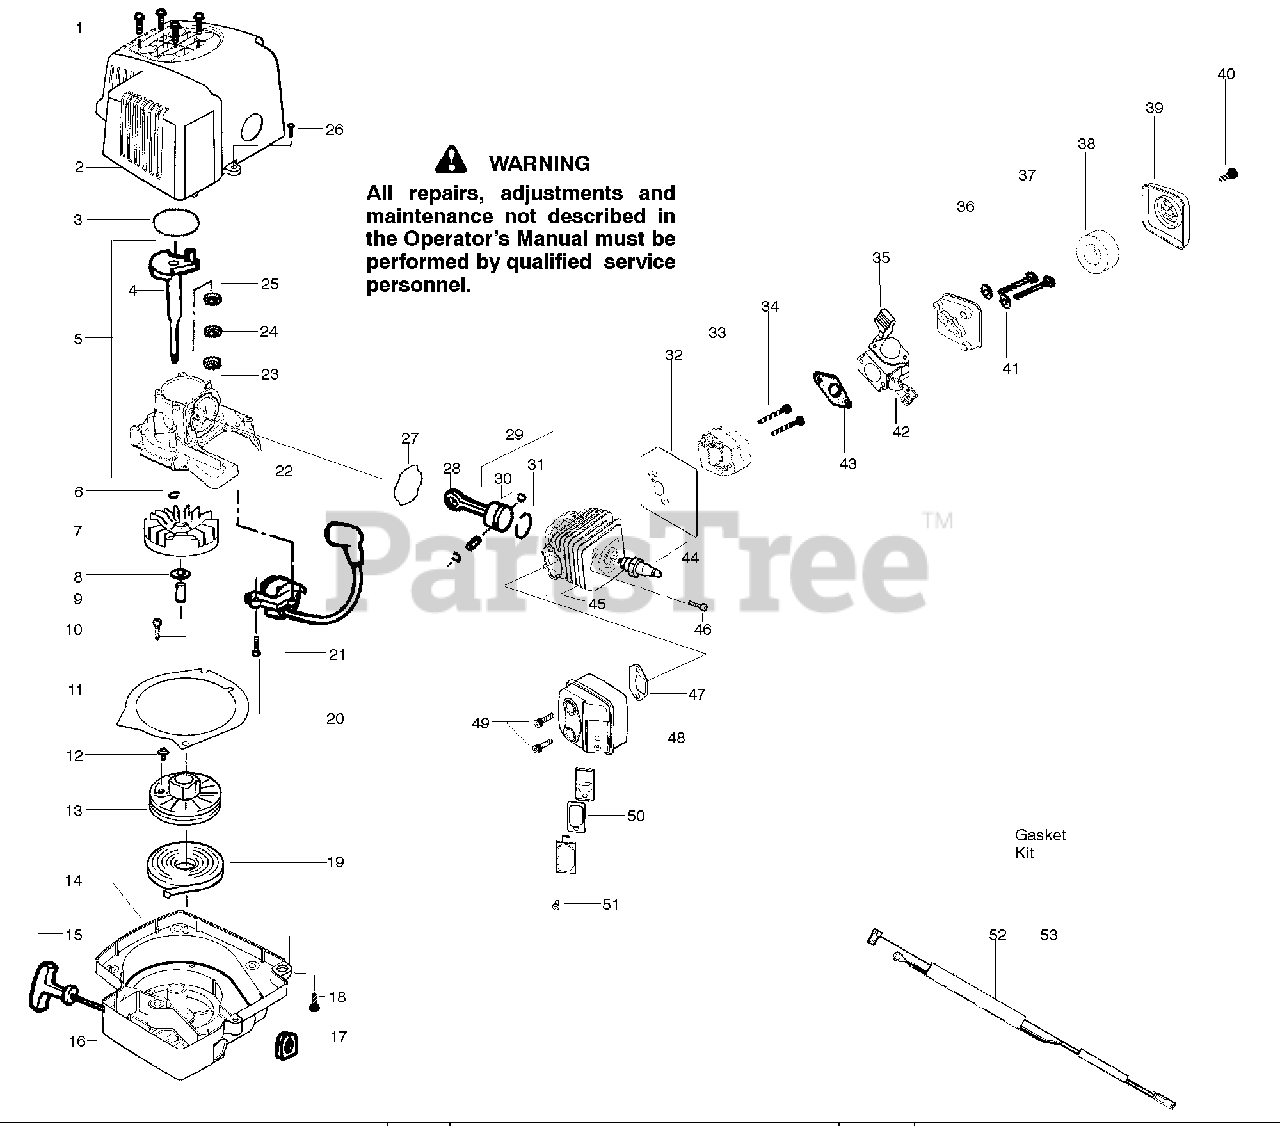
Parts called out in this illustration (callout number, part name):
2	Assy-Shroud/H'shield
3	O-Ring-C'case (kit)
4	Assy-Crankshaft
5	Assy-C/case-C/shaft
6	Ring-Retainer-C'shaft
7	Assy-Flywheel
9	Spacer-Flywheel
13	Kit-Starter Pulley
14	Assy-Fan Housing
15	Handle-Starter
17	Grommet-Ignition Module
18	Screw-(f/hsg to shrd)
19	Spring-Starter
21	Ignition Module
22	Assy-Crankcase
23	Bearing-Outer
24	Seal-Crankcase
25	Bearing-Inner
27	Seal-Cylinder (kit)
28	Assy-Connecting Rod
29	Kit-Piston
30	Retainer-Piston Pin
31	Ring-Piston
32	Gasket-Carb. Adapt.(kit)
33	Adapter-Carburetor
35	Kit-Choke Lever
38	Air Filter Foam
39	Air Filter Cover
41	Washer
42	Kit-Carburetor Ass'y. (C1U-W13A)
43	Gasket-Carburetor(kit)
44	Spark Plug(RCJ-6Y)
47	Gasket-Muffler (kit)
48	Kit-Muffler
50	Kit-Spark Arrestor
52	Assy-Leadwire
53	Kit-Gasket
